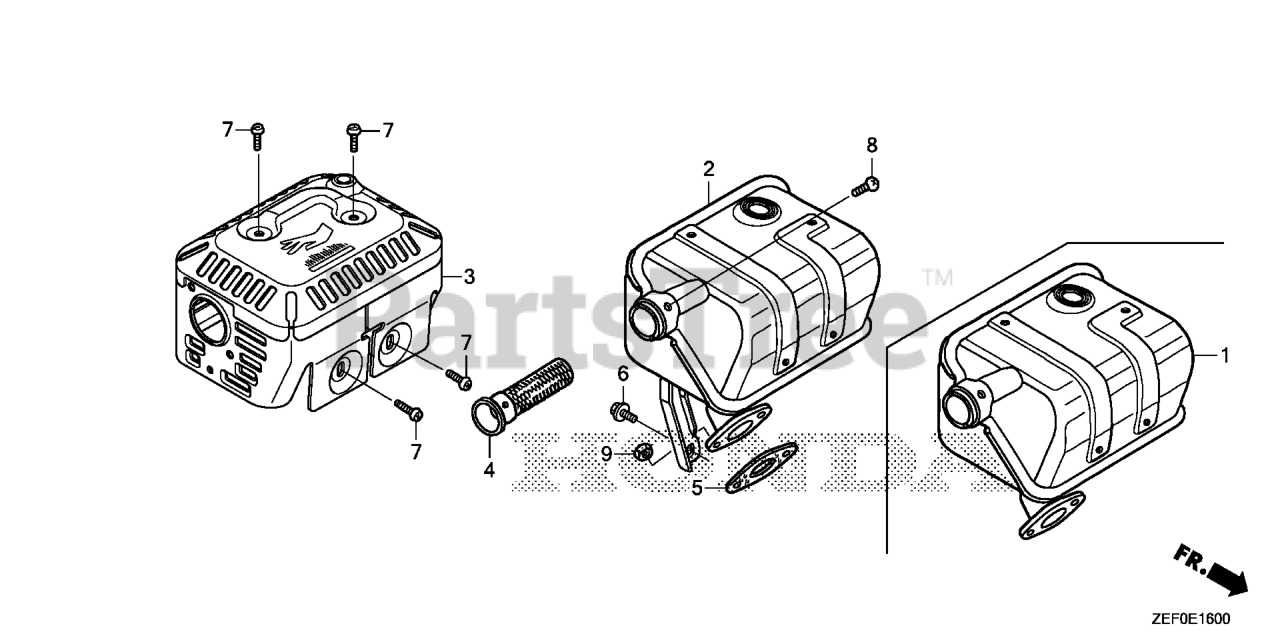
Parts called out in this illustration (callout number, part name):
2	MUFFLER
3	PROTECTOR, MUFFLER
4	ARRESTER, SPARK
5	GASKET, MUFFLER
6	BOLT, FLANGE (6X13)
7	SCREW, TAPPING (5X8)
8	SCREW, TAPPING (4X6) (TO INSTALL OPTIONAL SPARK ARRESTER)
9	NUT, HEX. (8MM)
